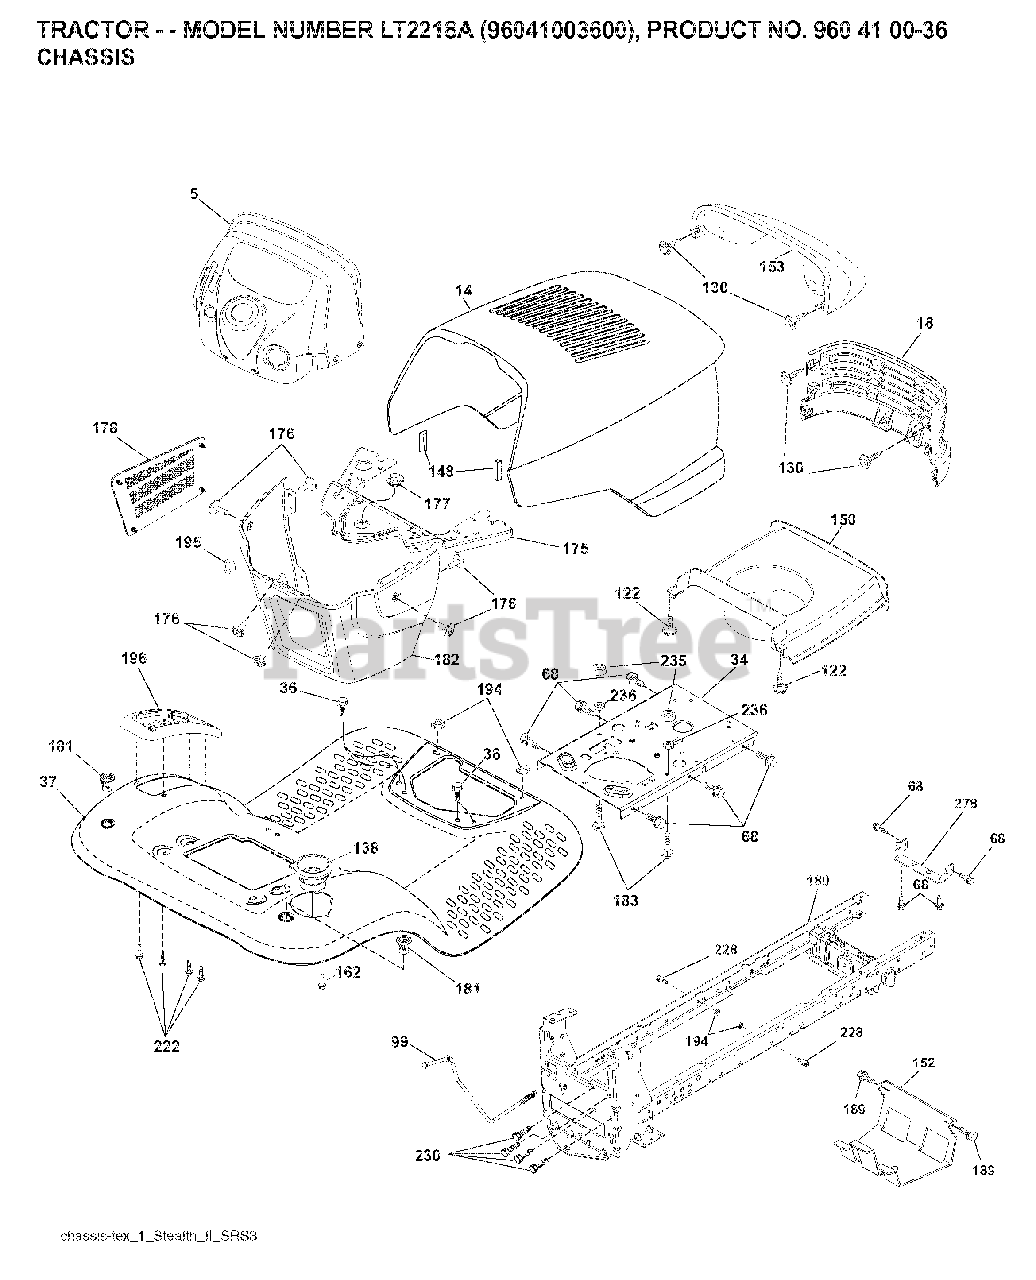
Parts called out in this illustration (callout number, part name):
34	PLATE.ENGINE.WELDED.CHASSIS
36	SCREW 5/16"
99	ROD.ASM.BYPASS.0510.HYDRO.LT
122	SCREW.WSHD.HEX10-32X5/8
130	SCREW
138	CUPHOLDER.TL.TEX.BLACK
148	EXTRUSION BUMPER
150	DUCT HOOD
152	SHIELD BROWNING
159	SCREW, 3/8-16X3/4
162	SCREW.HI-LO.CONSOLE
175	CROSSMEMBER.
176	SCREW.#10-24X5/8.RN.QU
177	BUSHING,STEERING
178	CARGO.ASM.NET.DASH.LOWER
180	CHASSIS
181	FEND/FTRST.PCH.CPH.NFW
182	DASH.LOWER.
183	BOLT.5/16-18X1-1/4 FULL.THREAD
189	SCREW
194	NUT LOCK HEX FLANGE 5/16-18
195	PLUG.HOLE.DASH.LOWER.12V.BLK
196	CONSOLE.ASM.DECK.LIFT.TLT.BLAC
222	SCREW.1/4-20X5/8
228	STUD.FASTNER.W/ANTI-ROTATE
230	SHOULDER BOLT 5/16-18TT
235	SPACER FENDER
236	NUT.CENTERLOCK.5/16-
278	BRKT.HOOD/MUFF.STEALTH
